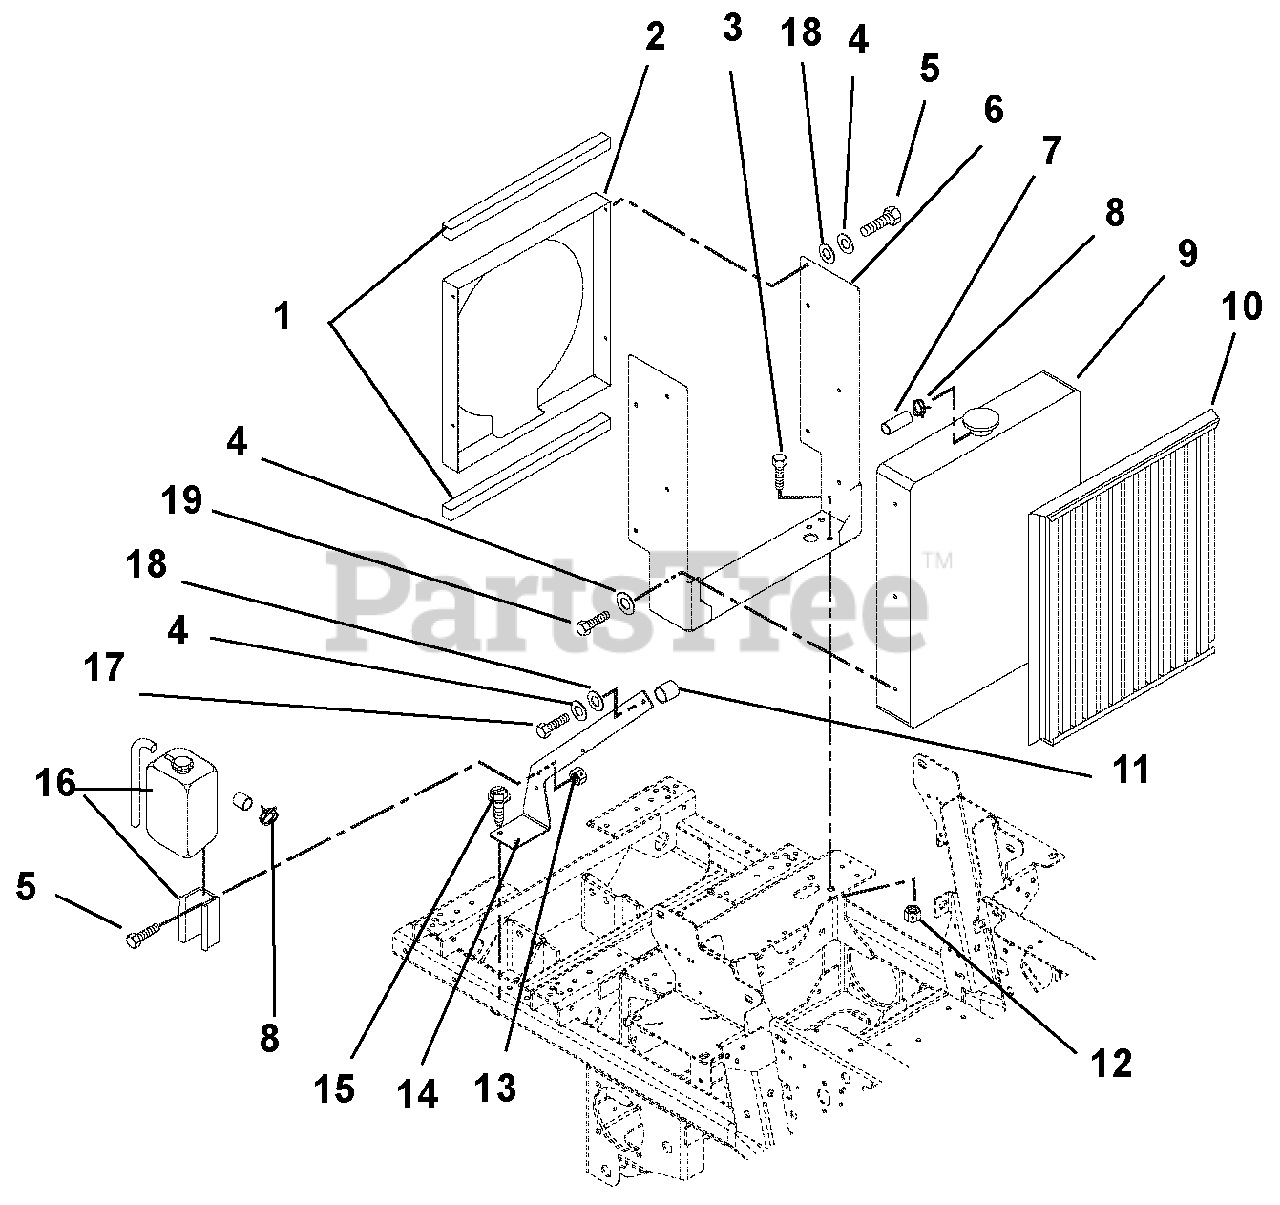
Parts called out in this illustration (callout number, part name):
1	Seal, Trim – LOK Bulk .06 Bubble
2	Weldment, Radiator Shroud
3	Bolt, Hex .38-16 x 1.00 Grade 5
4	Washer, Locking .25 x .062 Regular
5	Bolt, Hex .25-20 x .75 Grade 5
6	Bracket, Radiator Mounting
7	Hose, .31 ID
8	Clamp, Fuel Line
9	Radiator (Comes with the engine)
10	Screen, Radiator
11	Spacer .328 x .76 x 1.01
12	Nut, Locking Top Flange .38-16
13	Nut, Locking Top Flange .25-20
14	Bracket, Overflow Mounting
15	Screw, Tapping .38-16 x .75 Hex Washer Head
16	Reservior Overflow (Included with engine)
17	Bolt, Hex M6-1.00 x 45
18	Washer, Flat Steel .281 x .62 x .065
19	Bolt, Hex M6-1 x 16
